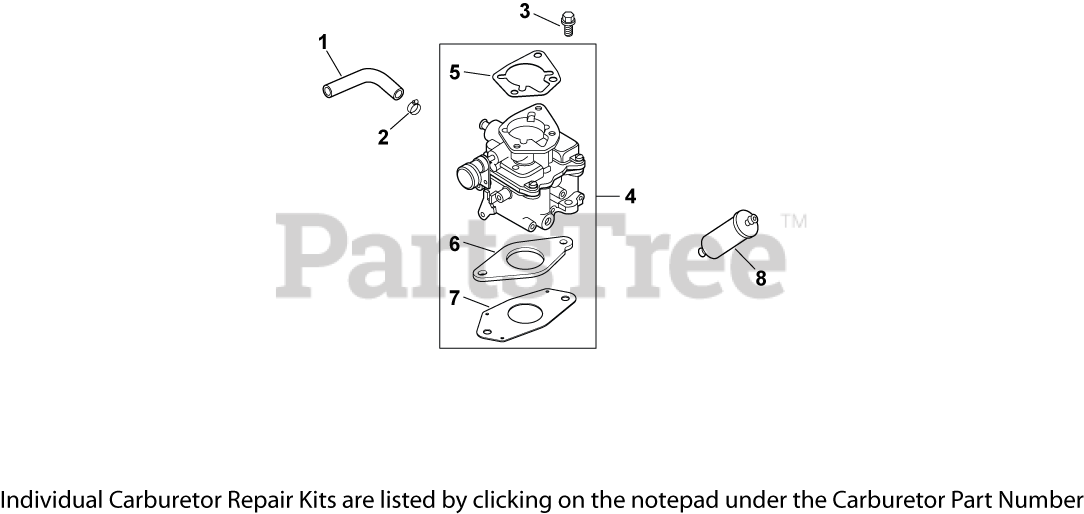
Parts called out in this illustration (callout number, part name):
1	HOSE,LW PERM.FUEL 24.00"-USE 25 111 81-S
2	CLAMP, HOSE (KM)-USE 25 237 31-S
3	SCREW, FLG M6X1.0X30
4	KIT, CARBURETOR W/GASKETS
5	GASKET, AIR CLEANER BASE
6	GASKET, CARBURETOR
7	GASKET, CARBURETOR
8	FILTER, FUEL
